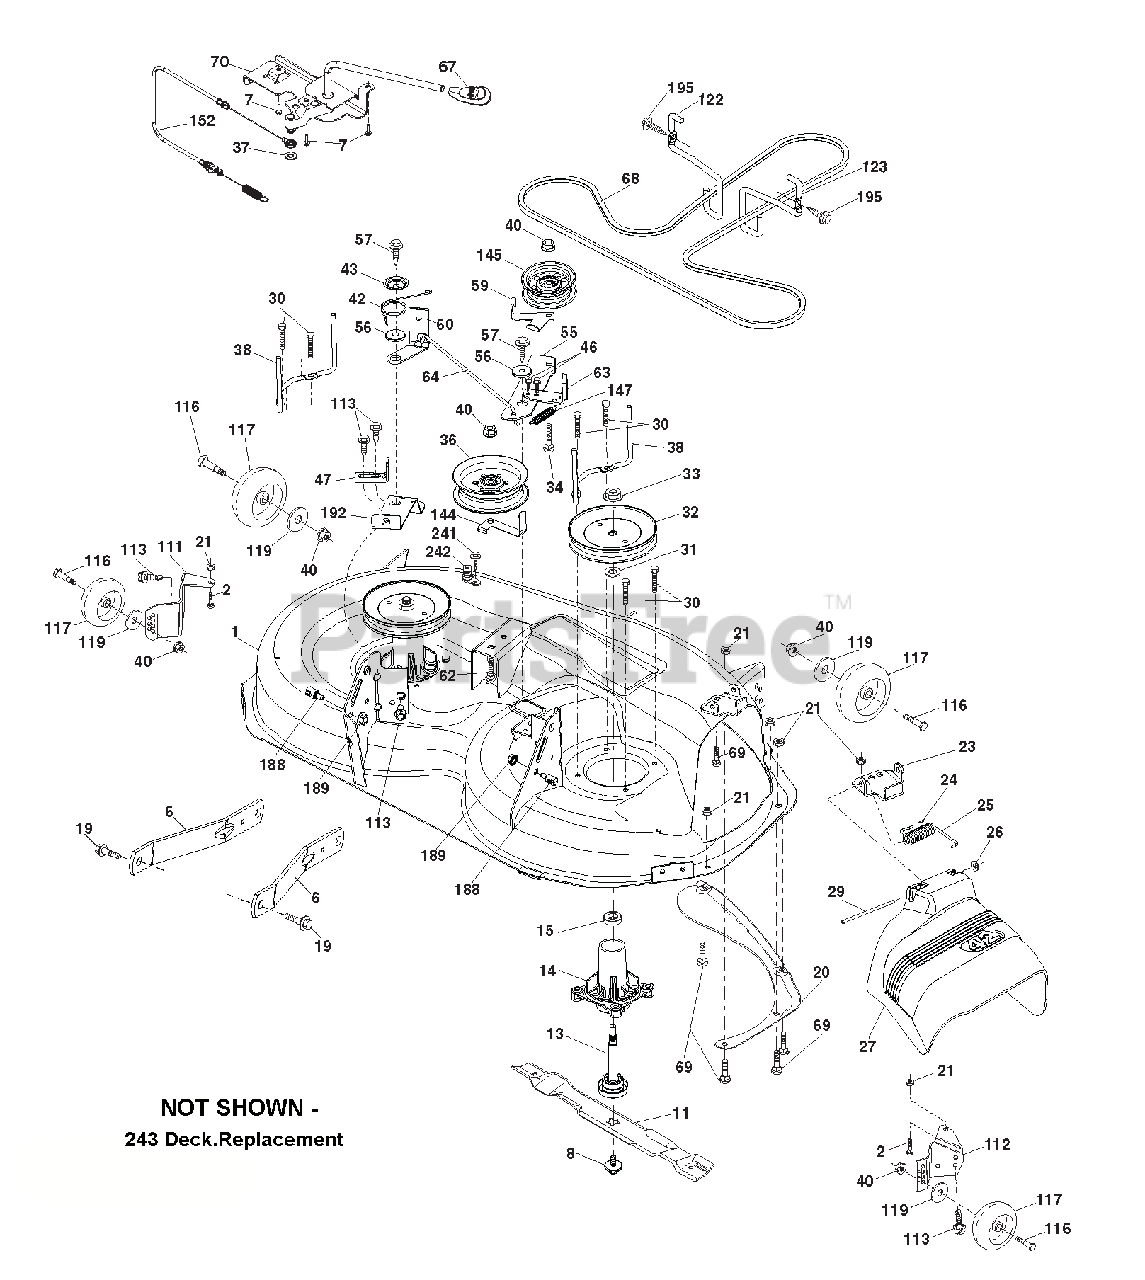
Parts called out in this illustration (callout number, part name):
1	DECK.WELDMENT.42"
6	ARM.SUSPENSION.MOWER.REAR.LD
8	BOLT/WASHER ASM.7/16-20.UNF
11	BLADE.MOWER.42"HI LIFT PREMIUM
13	SHAFT ASM.MNDRL.N/GREASEABLE38
14	HOUSING.MANDREL.4PT.SERVICE
15	BEARING.BALL.MANDREL
19	BOLT.SHOULDER
20	BAFFLE.VORTEX.42.STD/HEAVY DTY
21	Nut, Hex, Crownlock 5/16-18
23	BRACKET.DEFLECTOR.38/42"2005
24	CAP.SLEEVE..80X.112.BLK.MOWER
25	SPRING.TORSION.DFL.38/42/46.GR
26	NUT.PUSH.PHOS.& OIL
27	SHIELD.DEFLECTOR.
29	ROD.HINGE.42/46"
30	SCREW.THD ROLL.DOD PT.HEX
31	WASHER.SPACER.MANDREL
32	PULLEY.MANDREL.5.438 PD.42"
32	MANDREL ASM.SUB.N-GRS.4 BOLT
32	ONLY - PULLEY/WASHER AND BLADE BOLT/WASHERS NOT
32	INCLUDED)
33	NUT.FLANGE.LOCK.TOP
34	BOLT.CARR.SH.3/8-16X1-1/2.GR5
36	PULLEY.IDLER.4.50.RAW
37	WASHER.13/32 X 13/16 X 16 GA.
38	KEEPER.BELT.MANDREL.PULLEY
40	Nut, Hex, Flangelock 3/8-16
42	SPRING.TORSION.BRAKE
43	SPRING.TORSION.RETAINER
46	SCREW.THD.ROLL.1/4-20 X 5/8
47	BRACKET.CLUTCH.CABLE
55	IDLER.ARM
56	SPACER.RETAINER
57	SCREW.3/8-16X1.SMGML.TAP/R.BLK
59	GUARD.TUV.IDLER
60	ARM.BRAKE.MOWER.42"
62	BOLT.RD.HD.SQ.NK.3/8-16UNC X 2
63	ARM.BRAKE.MOWER
64	LINKAGE.BRAKE
67	HANDLE.CLUTCH.CABLE.LT TEX.428
68	BELT.DRIVE.100.97"
69	BOLT.RDHD.SQNK.5/16-18 X 5/8
70	CLUTCH.ASM.MANUAL
111	BRACKET WHEEL GAUGE LH
112	BRACKET WHEEL GAUGE RH
113	BOLT.5/16-18HEX.WHS.HD.LCKSERR
116	BOLD SHLD "A" 2.41 "B" 1.66
117	WHEEL.GAGE.HALF.SPOKED
119	Washer 3/8 x 7/8 x 14 Ga.
122	KEEPER.BELT.ENGINE.LH.LT.TEX
123	KEEPER.BELT.ENGINE.RH.LT.TEX
144	KEEPER.BELT.MOWER
145	PULLEY.IDLER 48"PRIMARY
147	SPRING.RETURN
152	CABLE.CLUTCH.MANUAL
188	STUD.FASTNER.W/'D'ANTI-ROTATIO
189	Nut, Lock Hex Flange 5/16-18 u
192	BRACKET.BRAKE.STAND.LH
195	SCREW.5/16-18X3/4.SMGML.TAP/BL
242	PORT WASHOUT
243	DECK.REPLACEMENT
